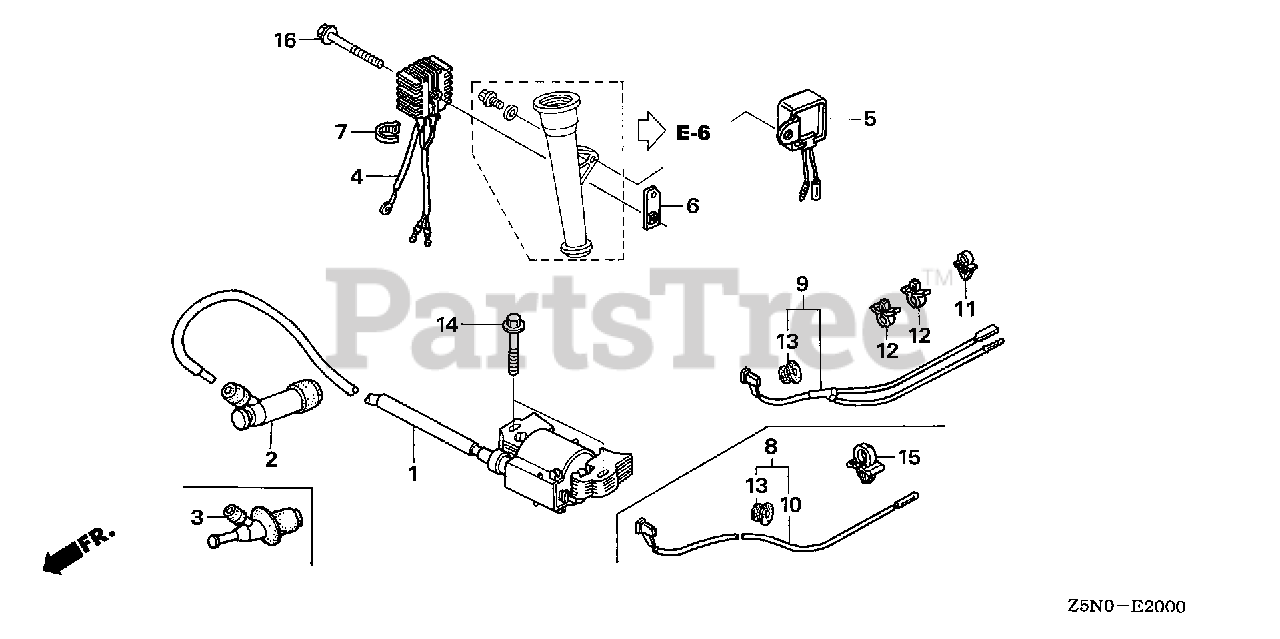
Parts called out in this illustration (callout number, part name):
1	COIL ASSY., IGNITION
2	CAP ASSY., NOISE SUPPRESSOR
9	WIRE, STOP SWITCH
11	HOLDER, STOP SWITCH WIRE
11	HOLDER, WIRE (FASTEX)
12	CLIP, BRAKE PIPE (A)
13	GROMMET, WIRE CORD
14	BOLT, FLANGE (6X28) (CT200)
